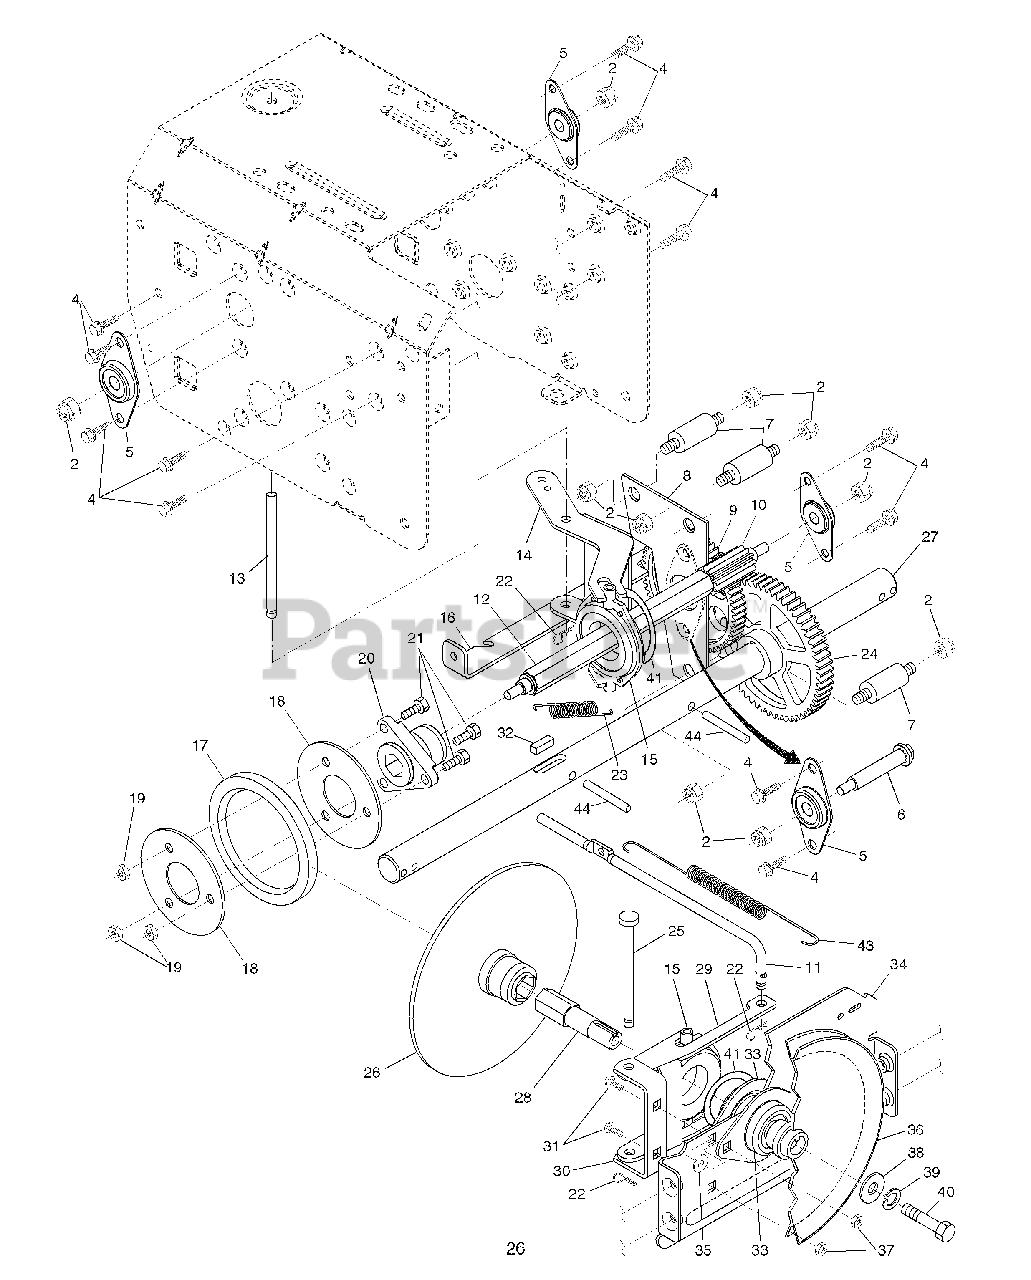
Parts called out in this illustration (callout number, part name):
2	Nut, Lock 5/16-18
4	Screw, Hex Head 5/16-18 x 1/2
5	Bearing, Flange
6	Shaft, Auxiliary
7	Spacer, Plate
8	Plate, Auxiliary
9	Gear, Intermediate
10	Gear, Pinion
11	Rod, Clutch
12	Shaft, Long, Hex
13	Pin, Pivot
14	Lever, Shifter / Wheel
15	Trunnion Bearing Assembly
16	Bracket, Pivot, Shift
17	Ring, Rubber Wheel
18	Plate, Rubber Wheel
19	Nut, Lock 5/16-18
20	Hub, Rubber Wheel
21	Screw, Hex Head 5/16-18 x 7/8
22	Retainer, Hairpin
23	Spring, Bias
24	Gear, Axle
25	Pin, Pivot Lever
26	Plate Assembly, Drive
27	Shaft, Axle
28	Shaft, Short Hex
29	Lever, Shifter Plate
30	Bracket, Shifter Support
31	Bolt, Carriage 5/16-18 x 5/8
32	Key, Square 1/4 x 1/4 x 7/8
33	Bearing, Flange
34	Plate, Drive Mounting
35	Spacer, Bearing
36	Pulley, Traction Drive
37	Nut, Lock 5/16-18
38	Washer, Flat
39	Washer, Lock 5/16
40	Screw, Hex Head 5/16-18 x 3/4
41	Ring, Retaining
43	Spring, Return
